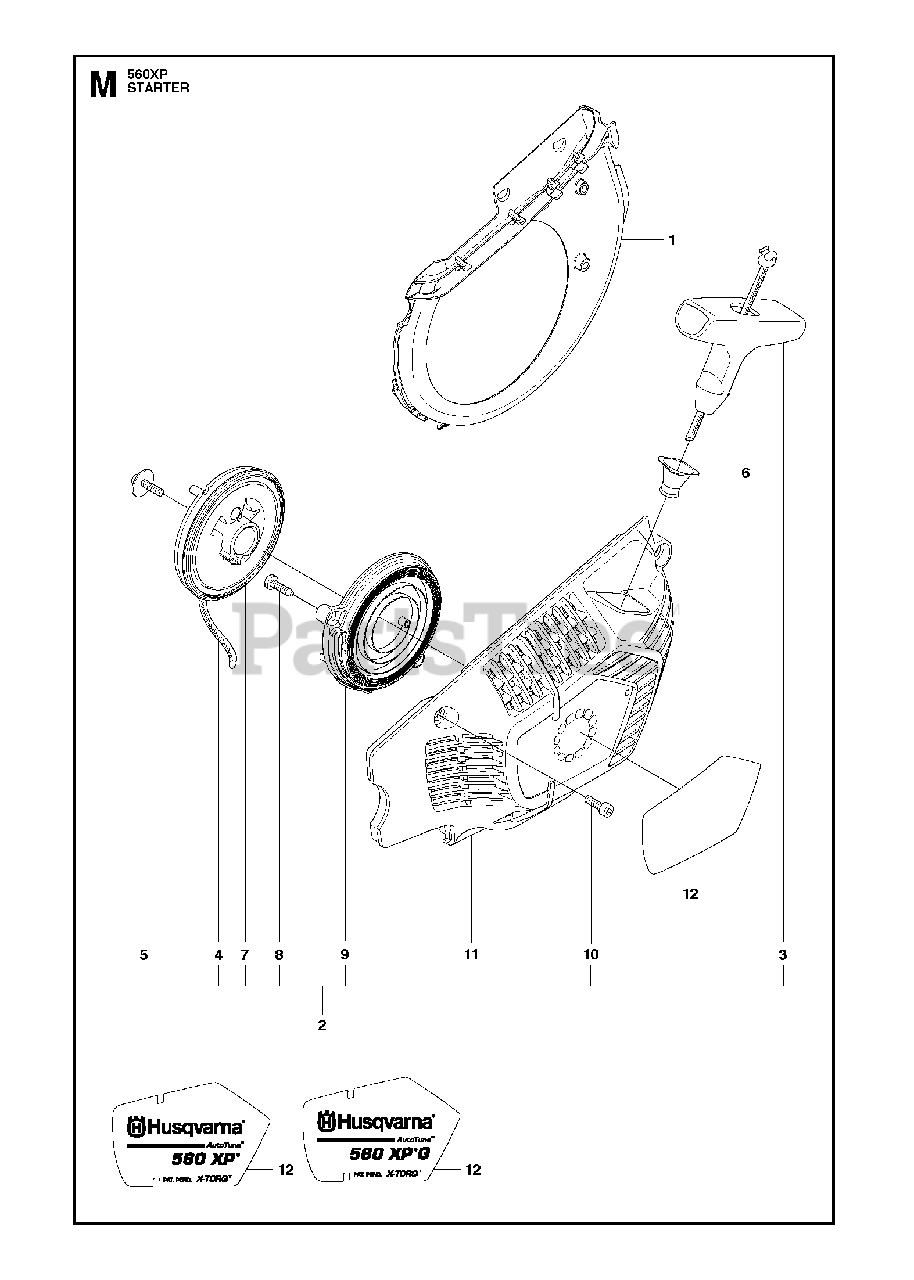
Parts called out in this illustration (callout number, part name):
1	COOLING AIR CONDUCTOR
2	RP STARTER ASSY
3	HANDLE
4	STARTER ROPE
5	SCREW
6	SLEEVE
7	STARTER PULLEY ASSY
8	SCREW
9	SPRING CASSETTE ASSY
10	SCREW
11	RP STARTER HOUSING
12	LABEL XP
12	LABEL XPG
